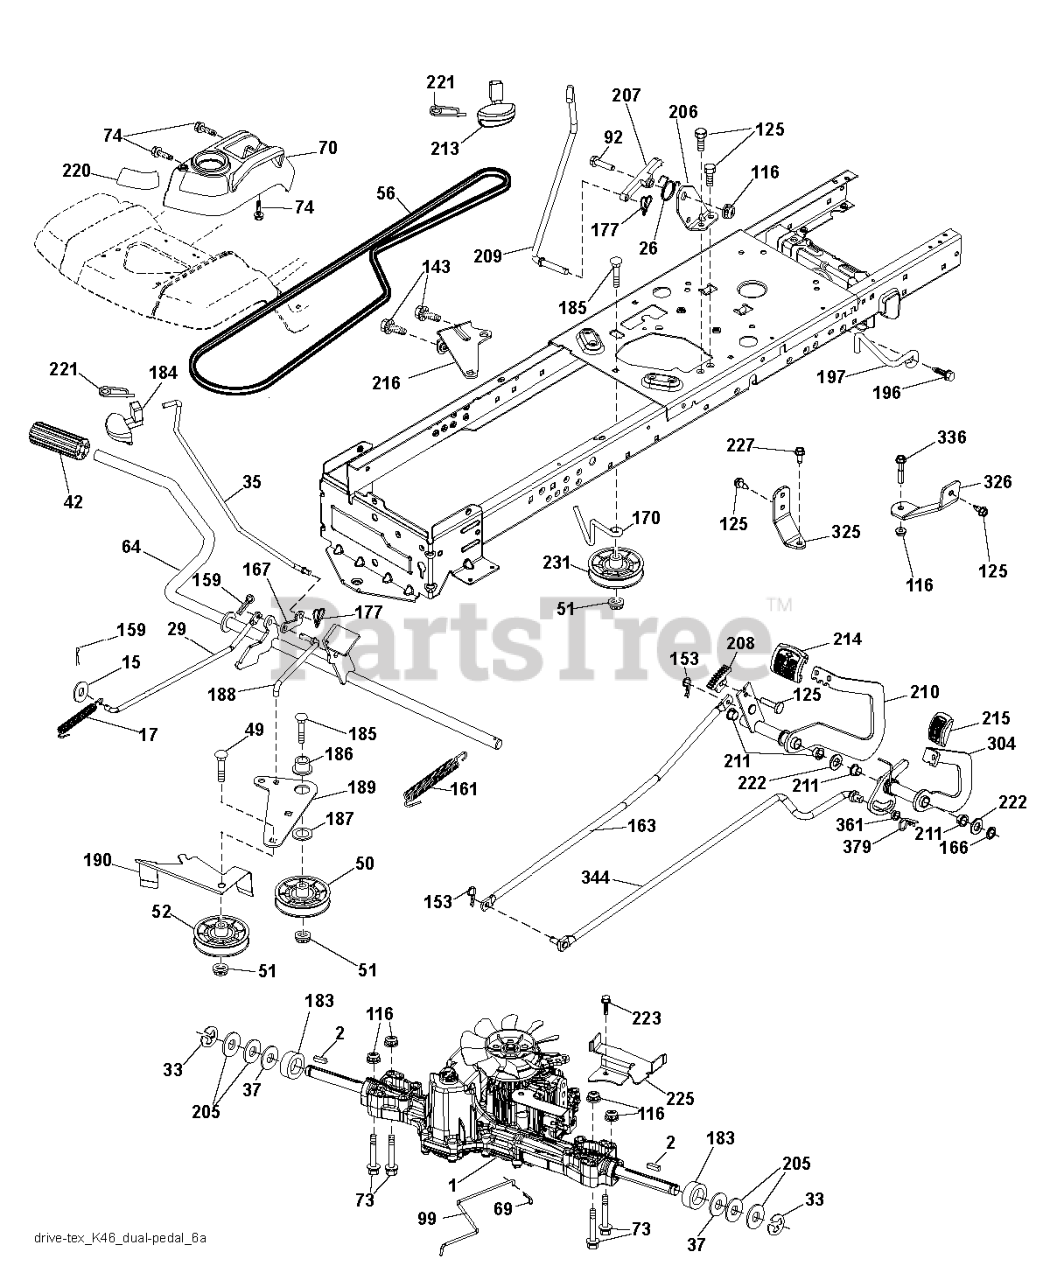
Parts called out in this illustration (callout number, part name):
1	TRANSAXLE.K46CR.PCH.ALD
2	SQUARE KEY
15	WASHER PLAIN WASHER 3/8 X 0.08
15	WASHER
17	SPRING.BRAKE.K46.GREEN
26	SPRING.RETURN.CRUISE
29	ROD.BRAKE.K46
37	WASHER.HARDENED
42	PEDAL COVER
50	IDLER.FLAT.910.OFFSET
51	NUT LOCK FLG 3/8-16 UNC
52	IDLER.V-GROOVE.910.OFFSET
64	SHAFT.ASM.PEDAL.BRK.CNTR
69	HAIRPIN.SOFT.ZINC.059X1.125
70	CONSOLE.ASM.RH.GT.FC.HUSQ
99	ARM.PIVOTING.TCRD.GEN2.5.BAGGE
125	SCREW
143	Screws
153	RETAINER M
161	SPRING, RETURN LT
163	Rods
166	NUT.PUSH.625
167	LATCH.BRAKE.SPRING
170	KEEPER.CENTER SPAN.1.688
170	KEEPER.V-IDLER.CENTER.
177	GSPW Retainers
177	PIN COTTER;LOCKING;BOWTIE;1IN
183	SPACER AXLE
184	HANDLE.PARKING.BRAKE.H (BLK)
186	SPACER.RETAINER
188	LINK.CLUTCH.GROUND DRIVE.LONG
189	BELLCRANK.GROUND.DRIVE.TEX.
190	KEEPER.BELLCRANK.DRIVE
196	SCREW 3/8-16X1
197	BRKT.42.FCS.CLUTCH.ANTIROTATIO
197	Stop
206	BRACKET.MOUNT.CRUISE.LATCH
210	Pedals
210	ROCKER.ASM.PEDAL.CONTR
211	BEARING.NYLON
213	KNOB.CONTROL.CRUSIE.HU
214	PEDAL.FORWARD.PAD.TEX
215	Pedals
215	PEDAL.COVER.REVERSE.CRD.X428BK
216	BRACKET.PULLEY.IDLER.W/TEX
220	REFLECTOR.RH.TEX GT
221	RETAINER.SPRING.CLIP.H
222	WASHER 21/32 X 1-1/4 X 10 GA.
225	KEEPER.BELT.TRANSAXLE.K46
231	IDLER.V-GROOVE.1.688.OFFSET
325	TORQUE.STRAP.K46.LT.LH
325	BRACKET.TRQ.STP.46.20".TIRE.LH
326	BRCKT.PNT.TRQ.STP.46.18TIRE.RH
326	BRCKT.PNT.TRQ.STP.46.20TIRE.RH
